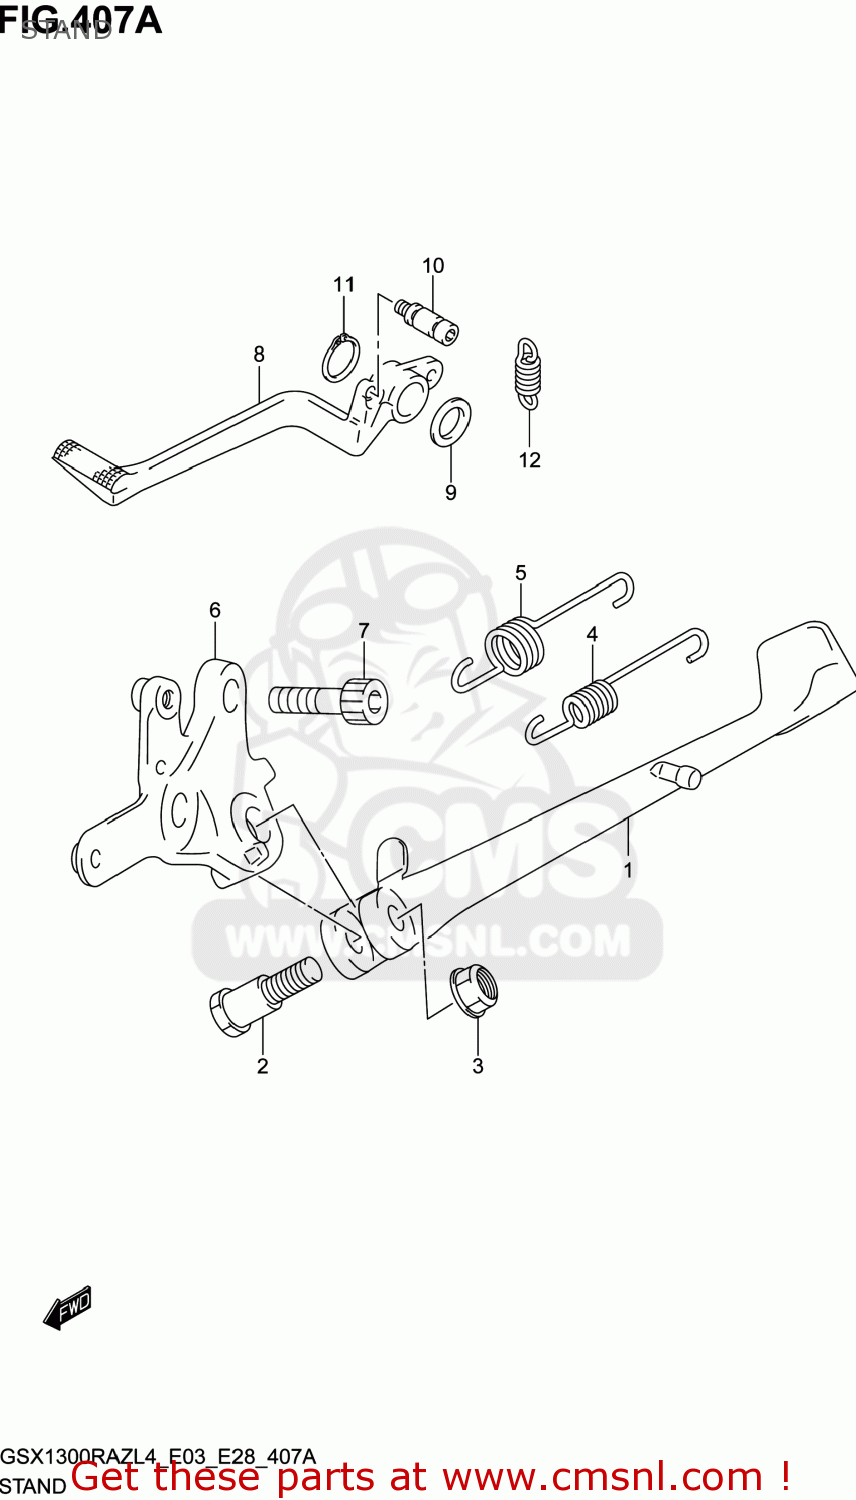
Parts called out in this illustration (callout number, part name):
1	STAND,PROP
2	BOLT(10X21)
3	NUT
4	SPRING
5	SPRING
6	BRACKET,PROP STAND
7	BOLT(12X35)
8	PEDAL,BRAKE
9	WASHER(18X24X1)
10	HOOK,RETURN SPRING
11	CIRCLIP
12	SPRING
